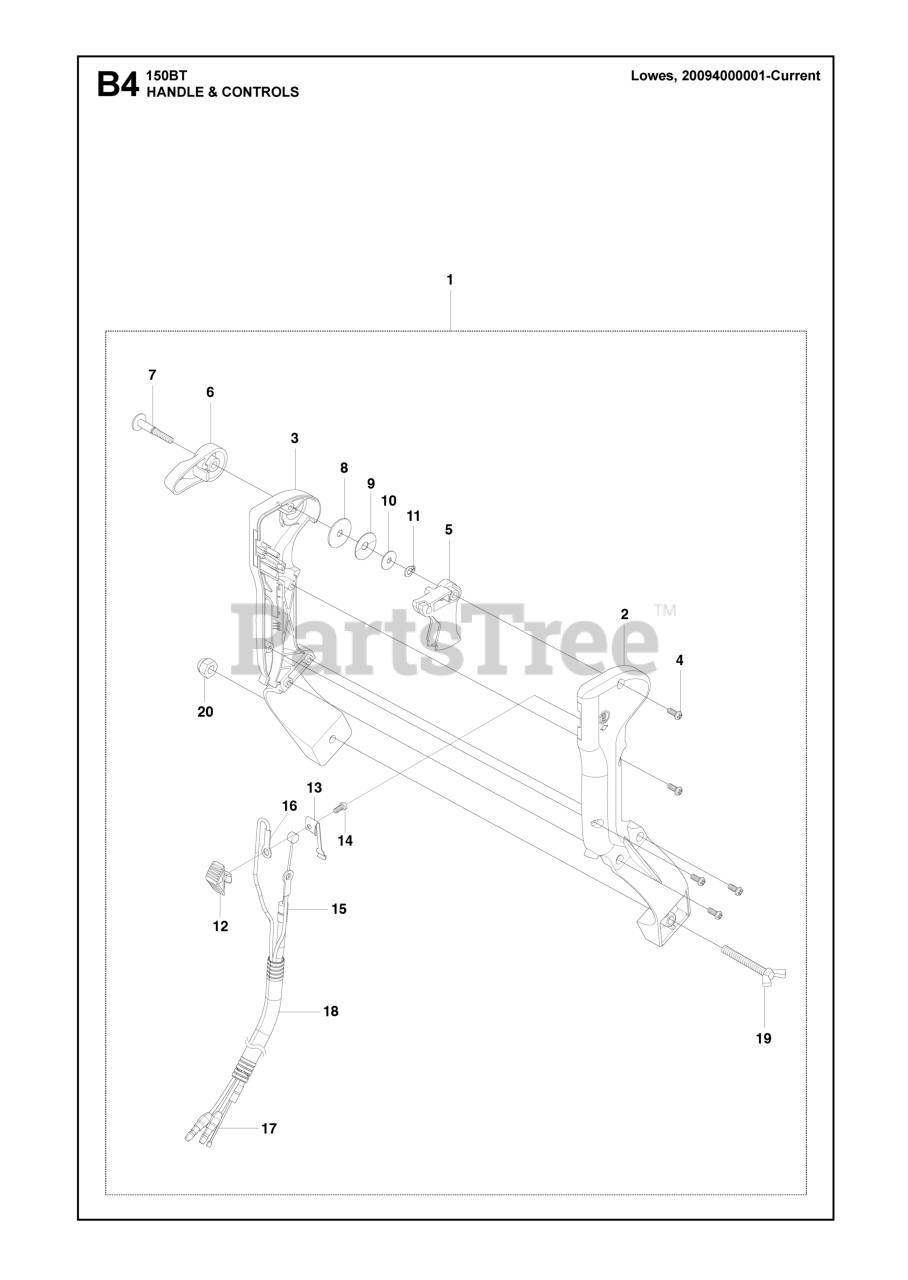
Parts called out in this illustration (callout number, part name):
4	SCREW 4X14(T)
5	LEVER THROTTLE
6	RP_LEVER (RPLS T402325430)
7	SHAFT
8	WASHER(T)
9	SPRING WASHER
11	RP_CLIP(T)
12	SWTICH (T)
13	SPRING (RPLS T402325720)
14	RP_SCREW 4X10(T)
18	TUBE (RPLS T402383210)
